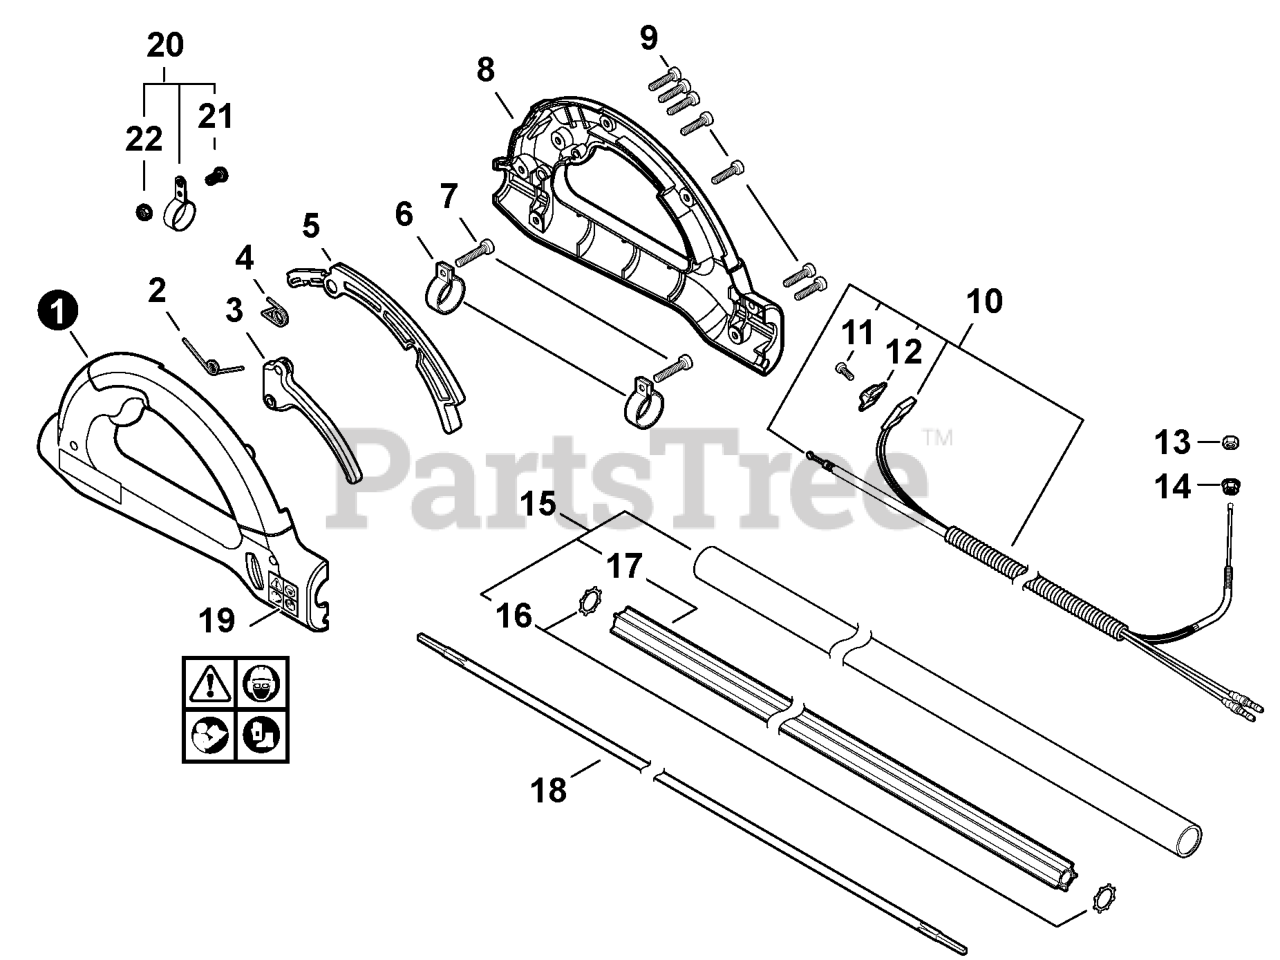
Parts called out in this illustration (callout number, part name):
1	BODY, HANDLE - LEFT
2	SPRING, TORSION
3	TRIGGER, THROTTLE
4	SPRING, TORSION
5	LOCKOUT, THROTTLE
7	BOLT, TORX 5x16
8	BODY, HANDLE - RIGHT
9	BOLT, TORX 5x16
10	CABLE ASSY, CONTROL
11	SCREW 3x10
12	KNOB, SWITCH - ORANGE
14	NUT, FLANGE M6
15	MAIN PIPE ASSY
17	LINER - FLEXIBLE
18	DRIVESHAFT - FLEXIBLE
19	LABEL - CAUTION - ISO
20	HANGER KIT
21	BOLT, TORX 5x10
22	NUT, M5x8 NYLON INSERT
